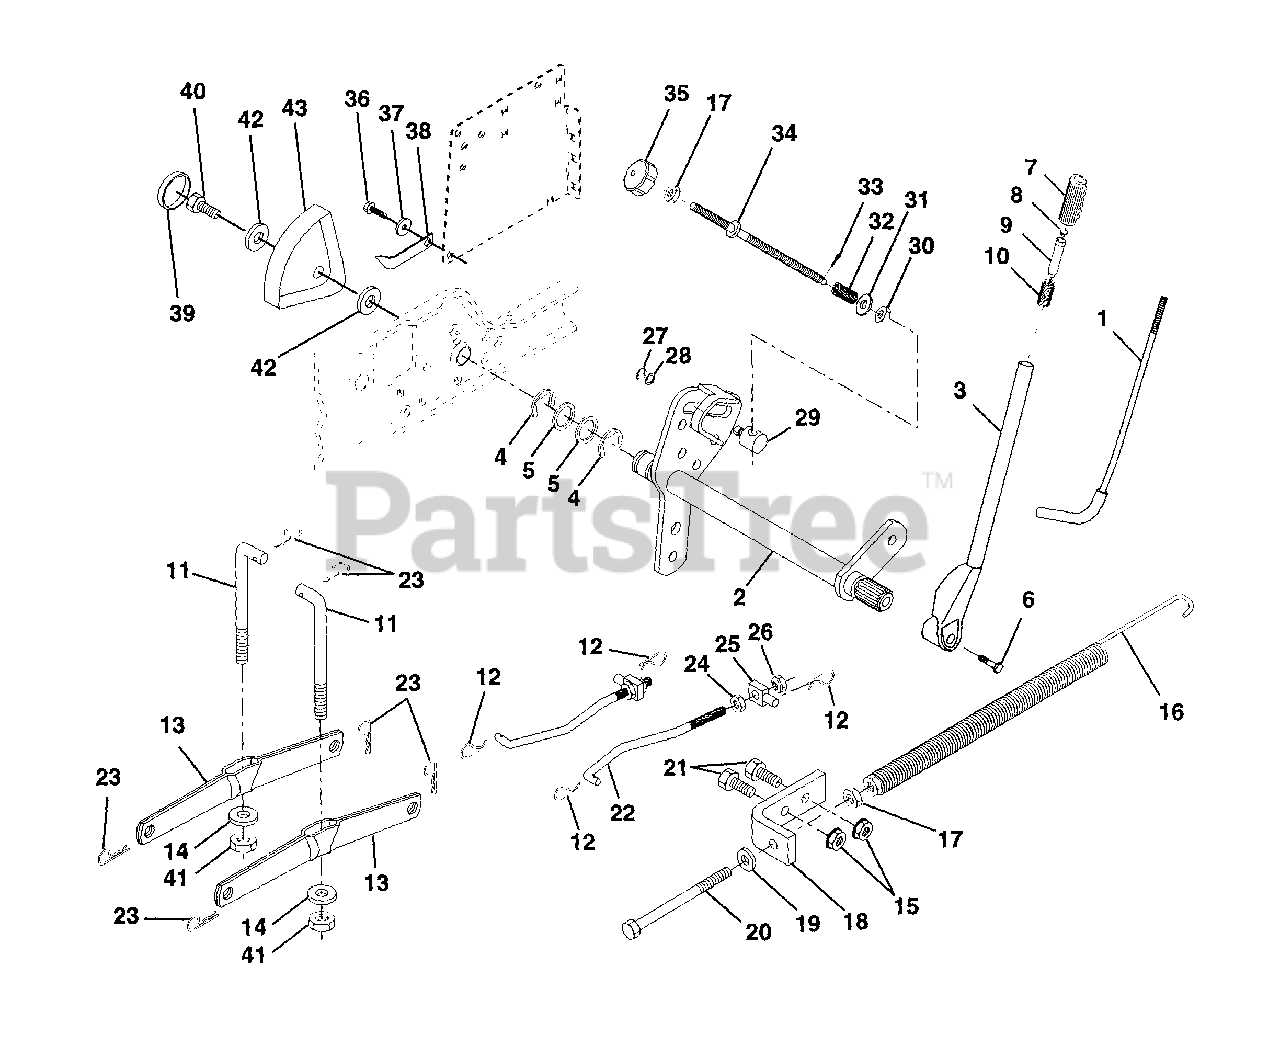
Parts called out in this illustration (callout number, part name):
1	Rod Asm., Lever
2	Shaft Asm., Lift Vgt
3	Lever Asm., Lift Rh
4	E-Ring Truarc #5133-87
5	Washer 29/32 x 1-1/4 x 16 Ga.
6	Bolt, Fin Hex 3/8-16 x 1-1/2
7	Grip, Handle Fluted
8	Button, Plunger
9	Plunger, Lever Lift
10	Spring 2-1/8"
11	Link Lift
12	Retainer, Spring
13	Arm, Suspension Vgt
14	Bearing
15	Nut, Crownlock 3/8-16 Unc
16	Spring Asm., Assist Lift
17	Nut, Hex Jam 3/8-16 Unc
18	Bracket, Spring Assist
19	Washer 13/32 x 13/16 x 16 Ga.
20	Bolt, Adjust Spring Assist
21	Bolt, Fin Hex 3/8-16 x 1
22	Link, Front
23	Retainer, Spring
24	Nut, Jam Hex 1/2-13 Unc
25	Trunnion
26	Nut, Lock W/Wsh 1/2-13 Unc
27	Ring, Klip #T5304-37
28	Washer 15/32 x 3/4 x 16 Ga.
29	Trunnion, Dp Stop Dbl Thds Plt
30	Nut, Special
31	Washer 13/32 x 5/8 x 16 Ga.
32	Spring, Compression Inf Hgt
33	Pin, Cotter 3/32 x 1/2
34	Rod, Adj Lift
35	Knob, Inf 3/8-16 Unc
36	Screw, Thdrol 3/8-16 x 3/4
37	Washer, Nylon
38	Pointer, Pnt Height Indicator
39	Plug, Hole
40	Screw Thdrol 5/16-18 x 3/4
41	Nut, Crownlock 3/8-24
42	Washer 11/32 x 1-1/2 x 10 Ga.
43	Scale, Indicator Height
